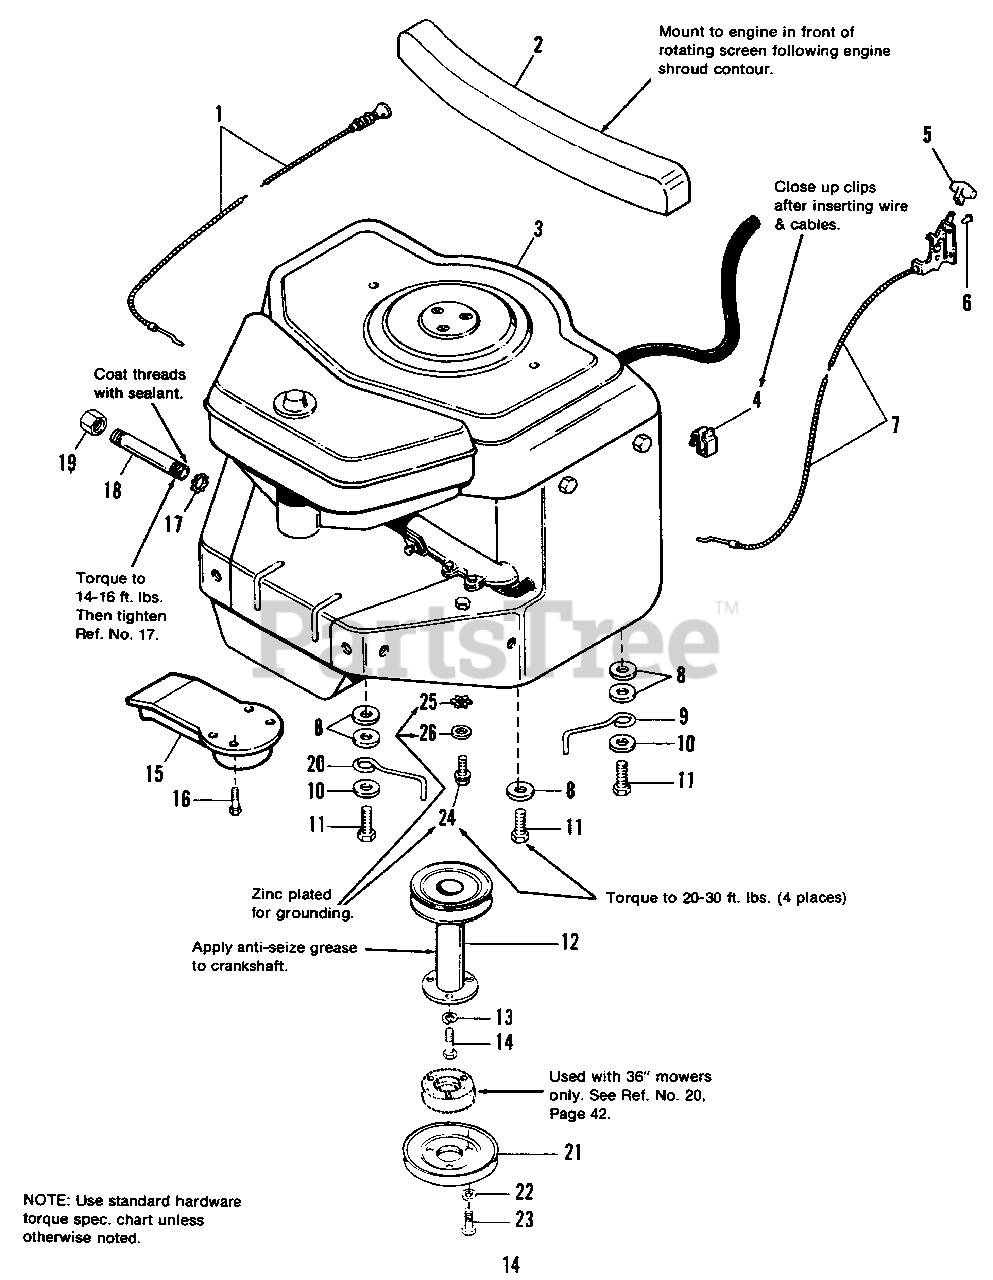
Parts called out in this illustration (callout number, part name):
1	CONTROL, Choke
2	BAFFLE, Engine, Rear
3	ENGINE, 16 HP, Briggs & Stratton
3	ENGINE, 12.5 HP, Briggs & Stratton
5	KNOB
6	RIVET, Pop
7	CONTROL ASSY.
8	WASHER, Plain
10	WASHER, Plain, 3/8
11	SCREW, Taptite, 3/8-16 x 1-1/2
12	PULLEY ASSY., Engine
13	LOCKWASHER, 7/16
14	CAPSCREW, Hex, 7/16-20 x 1-1/4
15	EXTENSION ASSY., Muffler
16	SCREW, Hex Thd., Cutting, #8-32 x 3/8
17	LOCKNUT, Conduit
18	PIPE, Oil Drain
19	PIPE, Cap, Hex
22	LOCKWASHER, 5/16
23	CAPSCREW, 5/16-18 x 1-1/2
24	SCREW, Taptite, 3/8-16 x 1-1/2, Zinc Pltd.
25	LOCKWASHER, Ext. Tooth, Zinc Pltd.
26	WASHER, Zinc Pltd.
